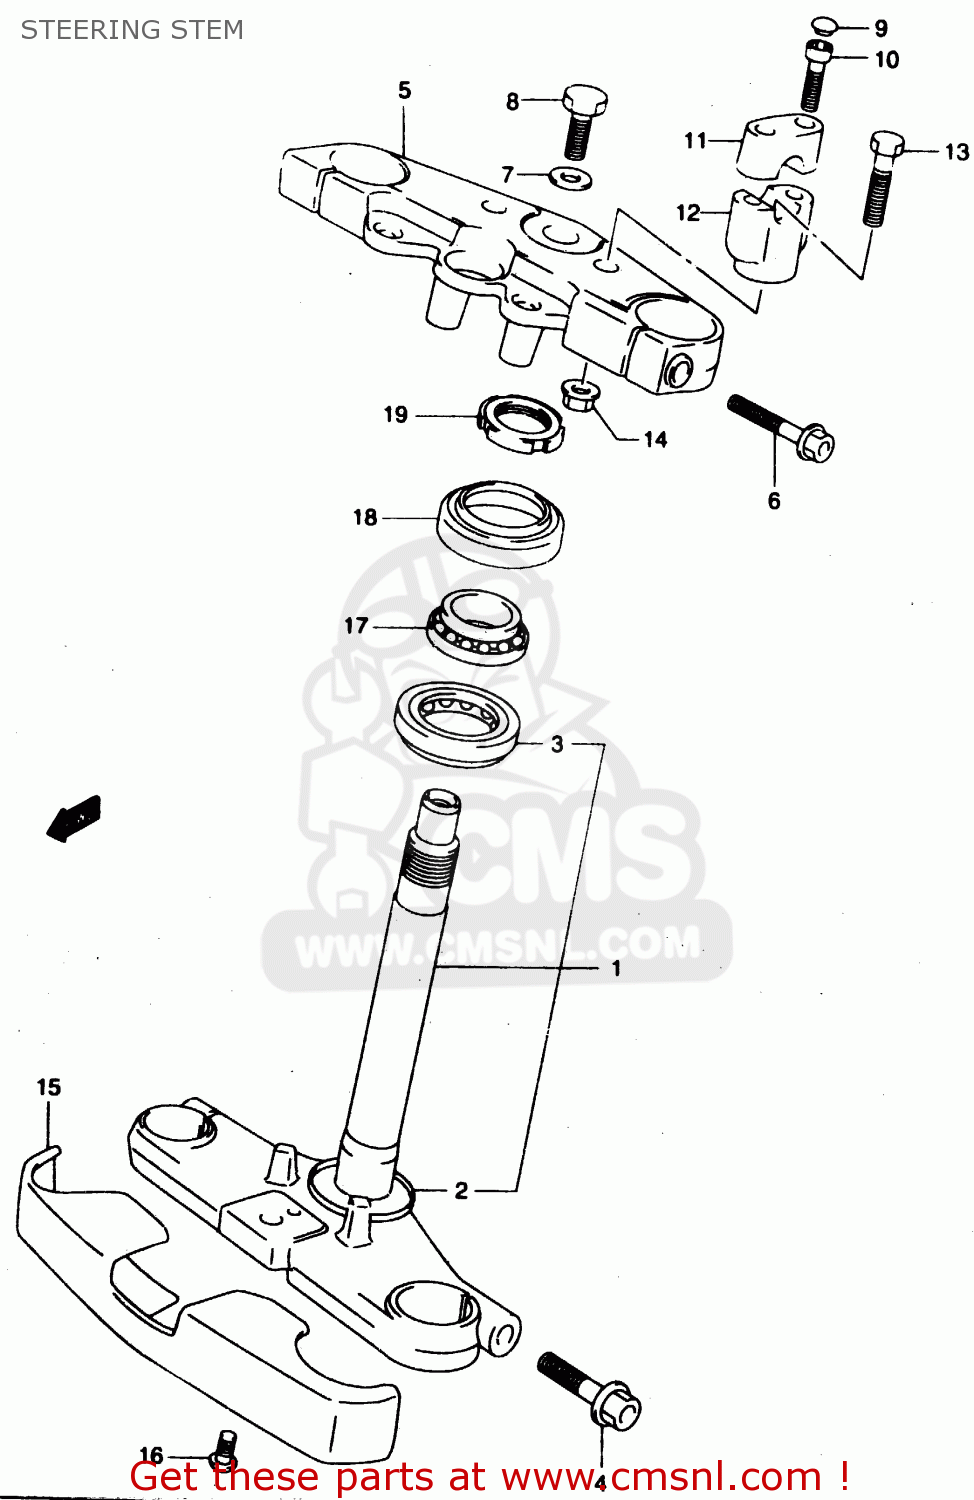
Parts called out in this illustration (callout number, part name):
1	STEM,STEERING
2	SEAL,STEERING LWR
3	BEARING(30X55X17)
4	BOLT
5	HEAD,STEERING STEM
6	BOLT
7	WASHER,STEERING STEM
8	BOLT,STEERING STEM HEAD
9	CAP(OD:11)
10	BOLT
11	HOLDER,HANDLE UPR
12	HOLDER,HANDLE UNDER
13	BOLT
14	NUT
15	COVER,FR FORK UNDER
16	SCREW(6X16)
17	BEARING(25X47X15)
18	DUST SEAL,STEERING UPR
19	NUT,STEERING STEM(25X44X10)
